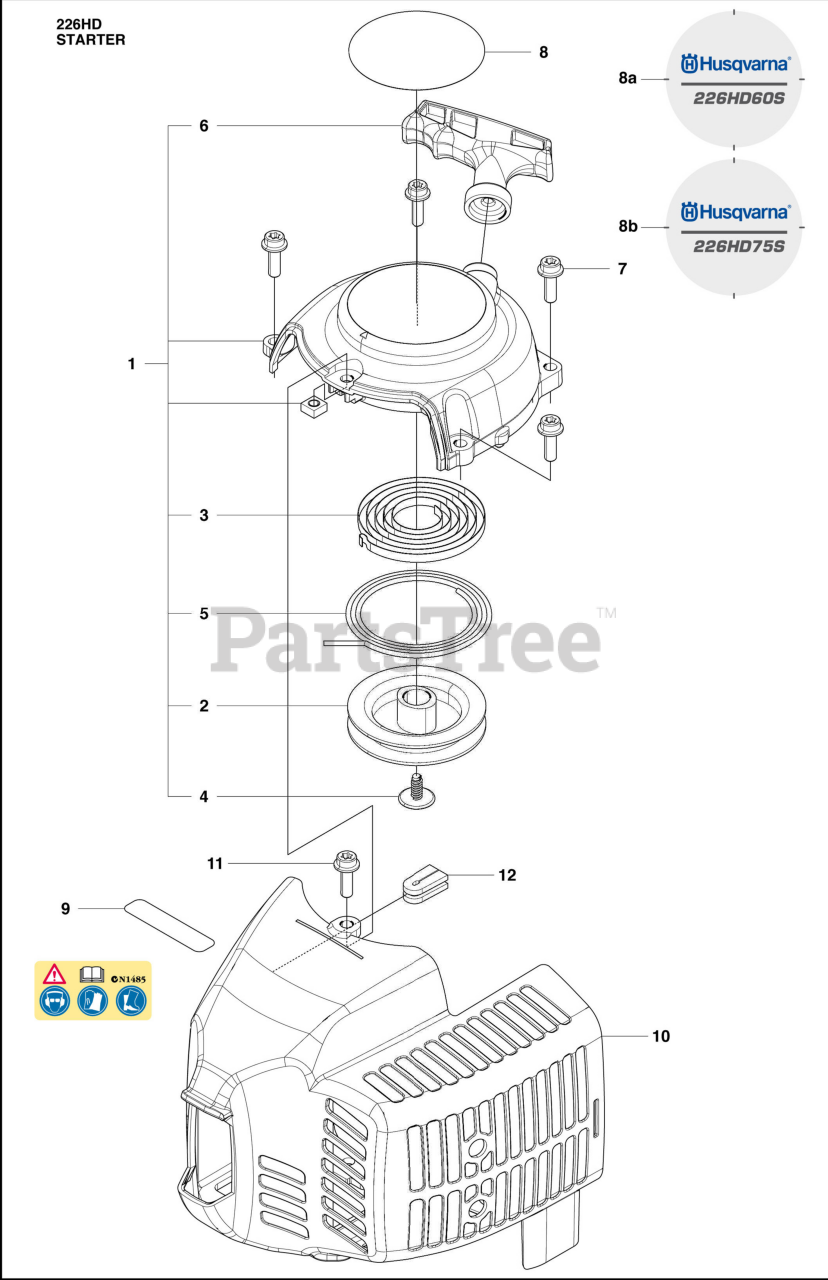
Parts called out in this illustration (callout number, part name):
1	Recoil Assembly
4	Screw
5	Starter Rope
7	Bolt
9	LABEL WARNING
10	Engine Cover
11	Bolt
